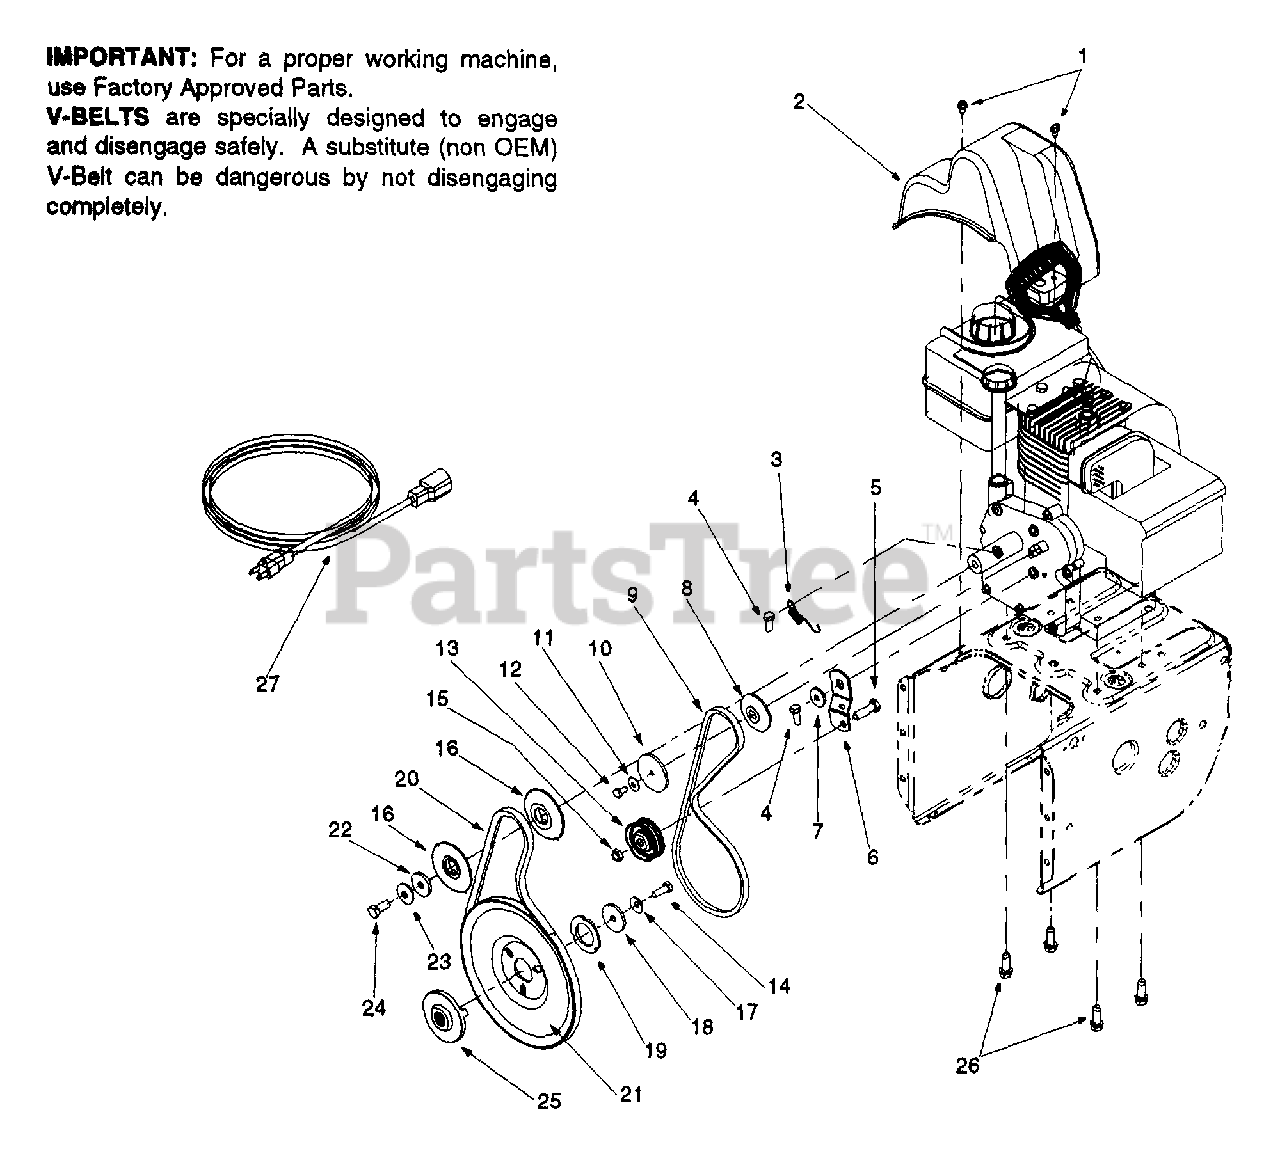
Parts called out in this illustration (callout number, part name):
1	Hex Washer Screw 1/4-20 x.5
2	Belt Cover
3	Extension Spring
4	Hex Screw 5/16-24 x .75
5	Hex Cap Screw 3/8-16 x 1.25
8	Pulley Half
9	V-Belt
10	Pulley Half
11	Bell Washer
12	Hex Cap Screw 1/4-28 x .50
13	Flat Idler
14	Lock Cap Screw 5/16-24
15	Lock Jam Nut 3/8-16
16	Pulley Half
17	Bell Washer
18	Flat Washer
19	Washer
20	Belt
21	Auger Pulley
22	Flat Washer
23	Bell Washer
24	Hex Cap Screw 3/8-24
25	Pulley
26	Hex Washer Screw 3/8-16 x 1.0
27	Extension Cord
